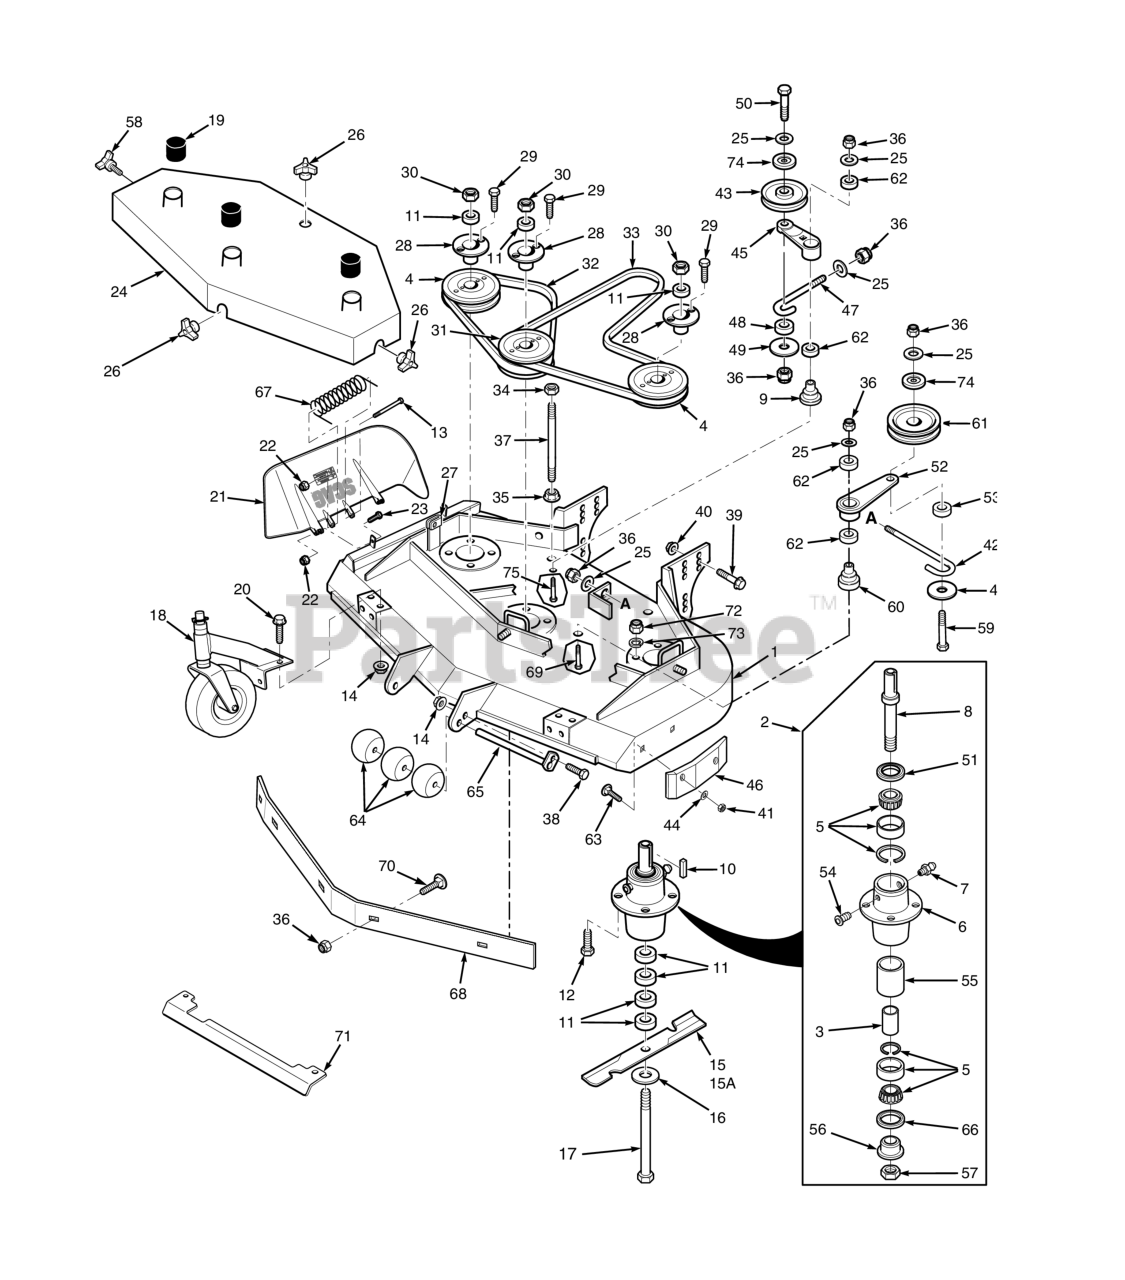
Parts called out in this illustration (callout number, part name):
1	Cutter Deck w/Decals
2	Cutter Spindle Assembly
3	SLEEVE, CUTTER SPINDLE
4	Pulley, 5.75 O.D. (Gasoline Engines)
5	Tapered Bearing Set (Two Bearings W/Race)
6	Housing, Spindle
7	GREASE FITTING, STR. 1/4-28 SELF TAP.
8	Spindle Shaft, Tapered Brng
9	Idler Pivot
10	Key, 1/4 x 1/4 x 2.0"
11	Spacer, Cutter Blade - Small
12	Bolt, Hex Head 5/16-18 x 1-1/2" Grade 8
13	Bolt, 5/16-18 x 4-3/4" Hex Head
14	Nut, Serrated Flange 5/16-18 (Right Front Engine Mounting, Briggs and Kohler Only)
15	Cutter Blade 18" (marbane)
15A	Cutter Blade 18" Hi Lift (marbane)
16	Flatwasher, 5/8-.688 x 1-3/4 x .134 HD
17	BOLT, HEX HEAD, 5/8-11 X 9-1/2 GR.5
18	Caster Assembly
20	Capscrew, 5/16-18 x .75 Serrated Flange Hex Head
21	Discharge Chute Assembly - 52V
22	HEX NUT, ELASTIC STOP LOCK, 5/16-18
23	Bolt, Hex Head 5/16-18 x 1-1/2" (Right Front Engine Mounting, Briggs and Kohler Only)
24	Belt Cover (Incl. decals)
25	Flatwasher, 3/8 (.391 x .938 x .105 HD) Grade 8
26	WINGNUT, PLASTIC 3/8-16 X .875
27	U-Nut, 3/8-16 (short)
28	Hub, Tapered 1-1/8" Bore
29	Bolt, Hex Head 1/4-20 x 1" Grade 8 Black
30	Hex Locknut, Elastic Stop, 3/8-16
31	Pulley, 5.75 Double Groove
32	BELT, RH BLADE DRIVE 52" DECK
33	Belt, Blade Drive
34	Bolt, Hex Head 3/8-16 x 1" Ser. Flg.
35	NUT, 3/8-16 SERRATED FLANGE HEX HEAD
36	HEX NUT, ELASTIC STOP LOCK, 3/8-16
37	Bolt, 5/16-18 x 1" Hex Head
38	Bolt, Heax Head 5/16-18 x 1" (48V / 52V)
39	Serr. Fl. Hex Head Capscrew, 1/2-13 x 1-3/4
40	Nut, Elastic Stop 1/2-13, (STT-52 & STTII-52)
41	Nut, Center Lock, 5/16-18(32)
42	J-HOOK, IDLER PULLEY
43	IDLER PULLEY, "V" GROOVE
44	Flatwasher, 5/16-.344 x .688 x .065 (48V / 52V)
45	Idler Arm Assembly
46	Pad, Deck Wear
47	J-HOOK, IDLER PULLEY
48	SPACER, J PULL ROD
49	Flatwasher, 3/8 (.375 x 1-1/2" x 16 ga.)
50	Capscrew, Hex Head 3/8-16 x 2-1/2"
51	SEAL, 2.00 O.D. X 1.50 BORE
52	Idler Arm Assy.
53	SPACER, J-PULL ROD
54	RELIEF FITTING, TAPERED BEARING SPINDLE
55	Spacer, Outside, Cutter Spindle
56	SPINDLE BUSHING, BOTTOM
57	Nut , Spec ial 1 -1/ 1 6 - 1 8
58	Knob, w/stud 3/8-16 x 1-1/4"
59	Capscrew, Hex Head 3/8-16 x 3-3/4"
60	Pivot, Idler - Short
61	Idler Pulley, Belt Clutch
62	BEARINGS, BALL, NEUTRAL RETURN
63	Bolt, 5/16-18 x .75 RHSN Carriage
64	Wheel, Anti-Scalp
65	Shaft Weldment, Guide Roller
66	Seal, 2.00" O.D. x 1.625" Bore
67	Spring, Discharge Chute
68	Baffle Custom-Cut, 52V (7-Position)
69	Capscrew, Hex Head 3/8-16 x 3.25"
70	Carriage Bolt, 3/8-16 x 1.0"
71	Heatshield, 16" Small Frame
72	Lock Nut, 5/16-18 Elastic Stop Grade 8
73	Lockwasher, 5/16 (.317 x .586 x .078) Helical Spring
74	Quick Pin, 5/16" Dia.
75	Capscrew, Hex Head 3/8-16 x 2.75"
